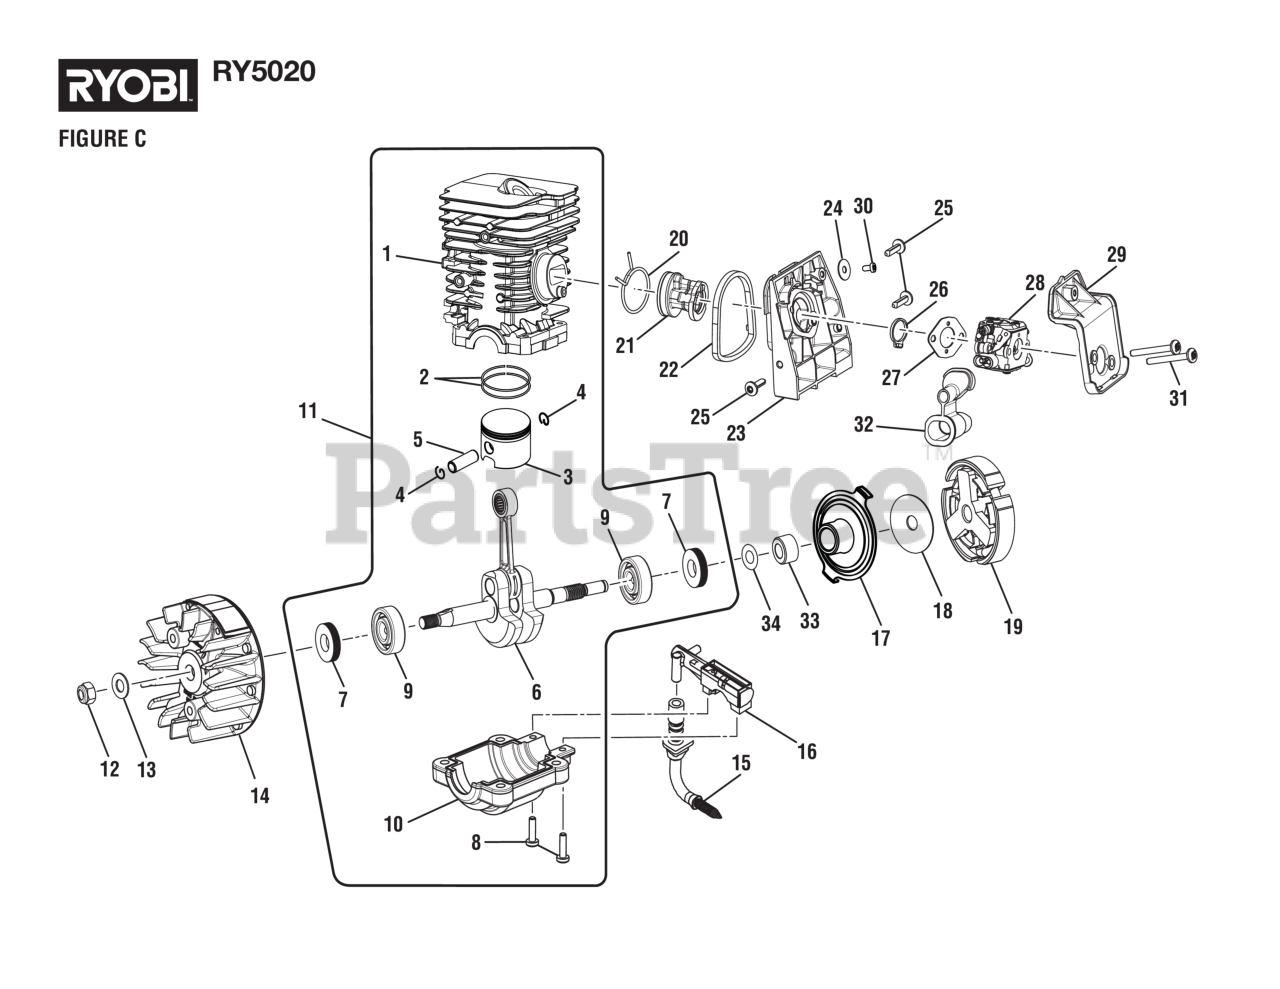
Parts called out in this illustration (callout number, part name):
2	Piston Ring
4	Spring Retainer
5	Piston Pin
6	Crankshaft Assembly
7	Shaft Seal
8	SCREW, (8/32 X 5/8 in. PAN HD TORX)
9	Ball Bearing
10	Crankcase
11	Short Block Assembly
12	Lock Nut (M8)
13	Washer (ID9 x OD17.7 x 1.1t)
14	Flywheel Assembly
15	OIL INTAKE TUBE W/FILTER
16	Oil Pump Assembly
17	Oil Pump Driver
18	Thrust Washer
19	Clutch Assembly
20	Wire Clamp
21	INTAKE BOOT
22	Carburetor Adaptor Seal
23	Carburetor Adapter
24	Flat Washer
25	Screws (10-14 x 3/4 in., T25 Torx Pan Hd. T.F.)
26	PLATE, CARBURETOR
27	Carburetor Gasket
28	Carburetor Assembly
29	Air Filter Base
30	Screw (#8-16 x 5/16 in., T25 Torx Pan Hd. T.F.)
31	Screw (10-32 x 1 3/4 in.)
33	Bearing (Oil Pump Driver)
34	Washer (Oil Pump Drive Gear)
